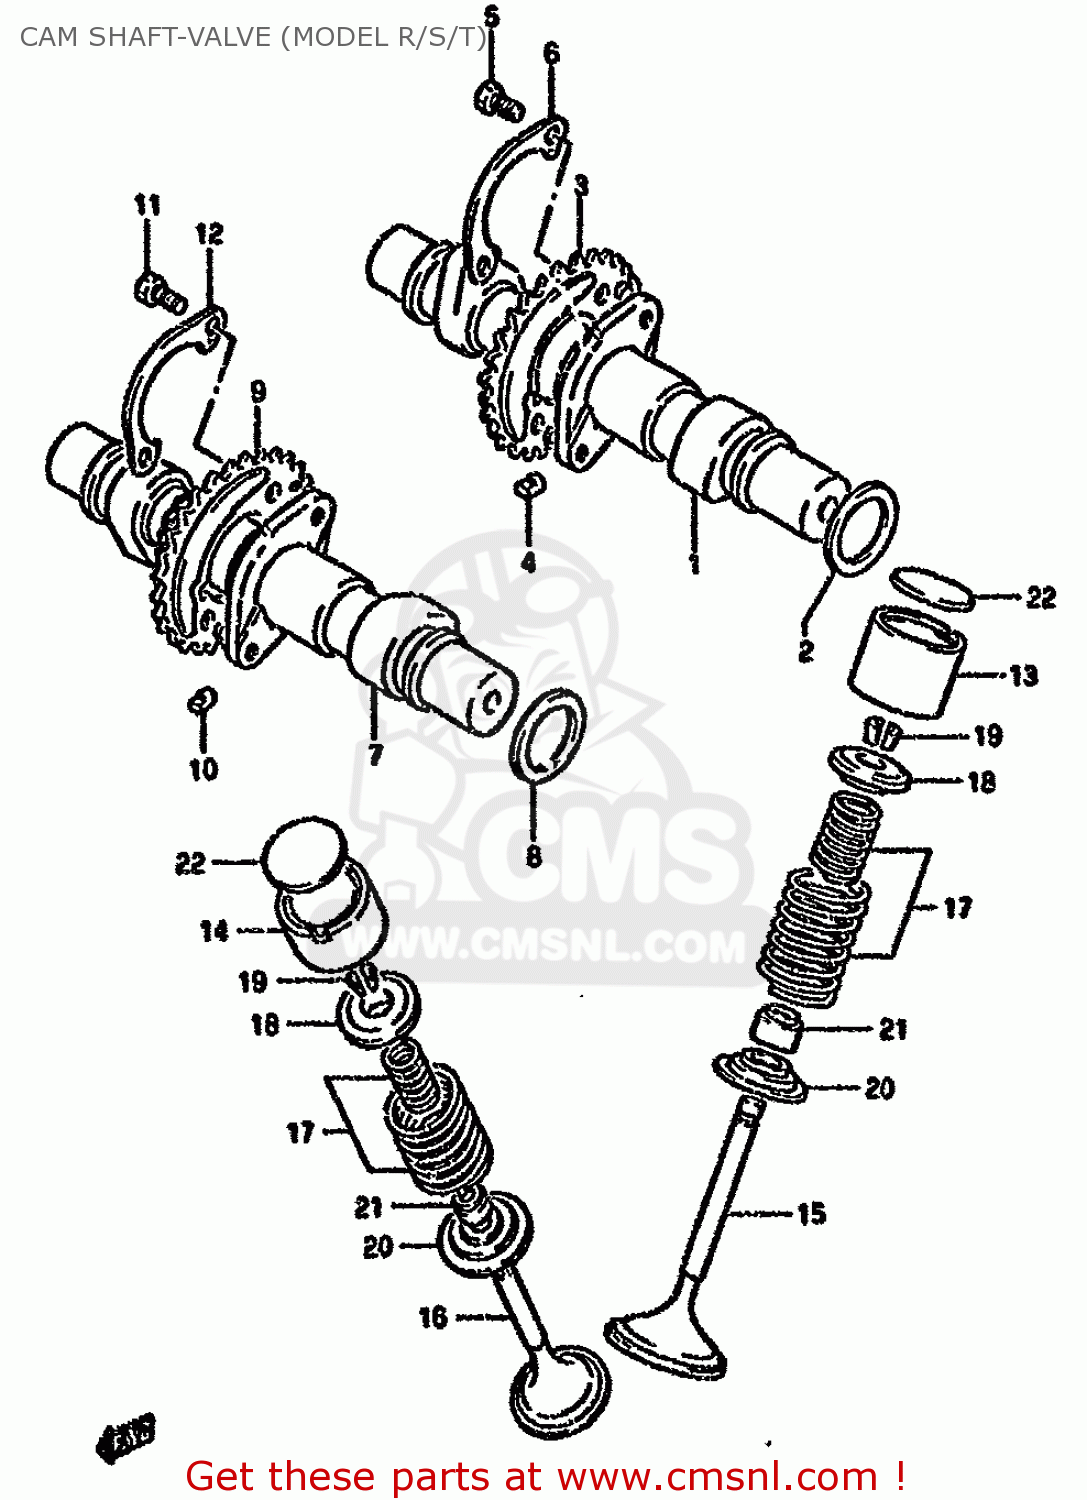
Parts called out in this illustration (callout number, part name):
1	CAMSHAFT SET,INTAKE
2	WASHER,THRUST
3	SPROCKET,CAMSHAFT INTAKE
4	PIN,SPROCKET
5	BOLT(6X12.5)
6	WASHER,CAM CHAIN SPROCKET
7	CAMSHAFT SET,EXHAUST
8	WASHER,THRUST
9	SPROCKET,EXHAUST CAM(NT:30)
10	PIN,SPROCKET
11	BOLT(6X12.5)
12	WASHER,CAM CHAIN SPROCKET
13	TAPPET
14	TAPPET
15	VALVE,INTAKE
16	VALVE,EXHAUST
17	SPRING SET,VALVE
18	RETAINER,VALVE SPRING
19	COTTER VALVE
20	SEAT,VALVE SPRING
21	SEAL,OIL(7X14.4X9)
22	SHIM,TAPPET(T:2.15)
